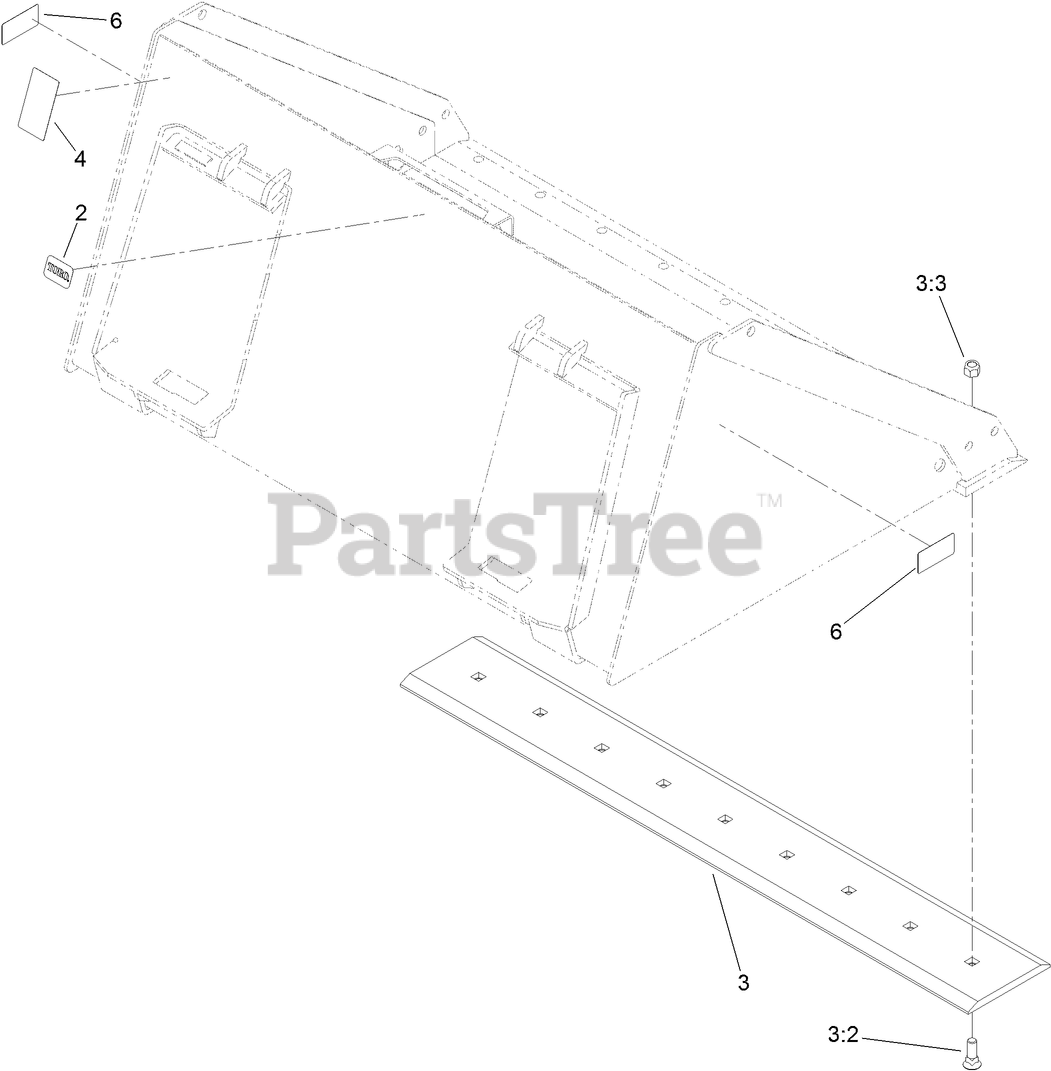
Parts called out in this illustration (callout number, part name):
2	DECAL
3	54IN BOLT ON EDGE KIT
3:2	BOLT-PLOW
3:3	NUT-LOCK, NI
4	DECAL-WARNING, CAPACITY
6	DECAL-DANGER
